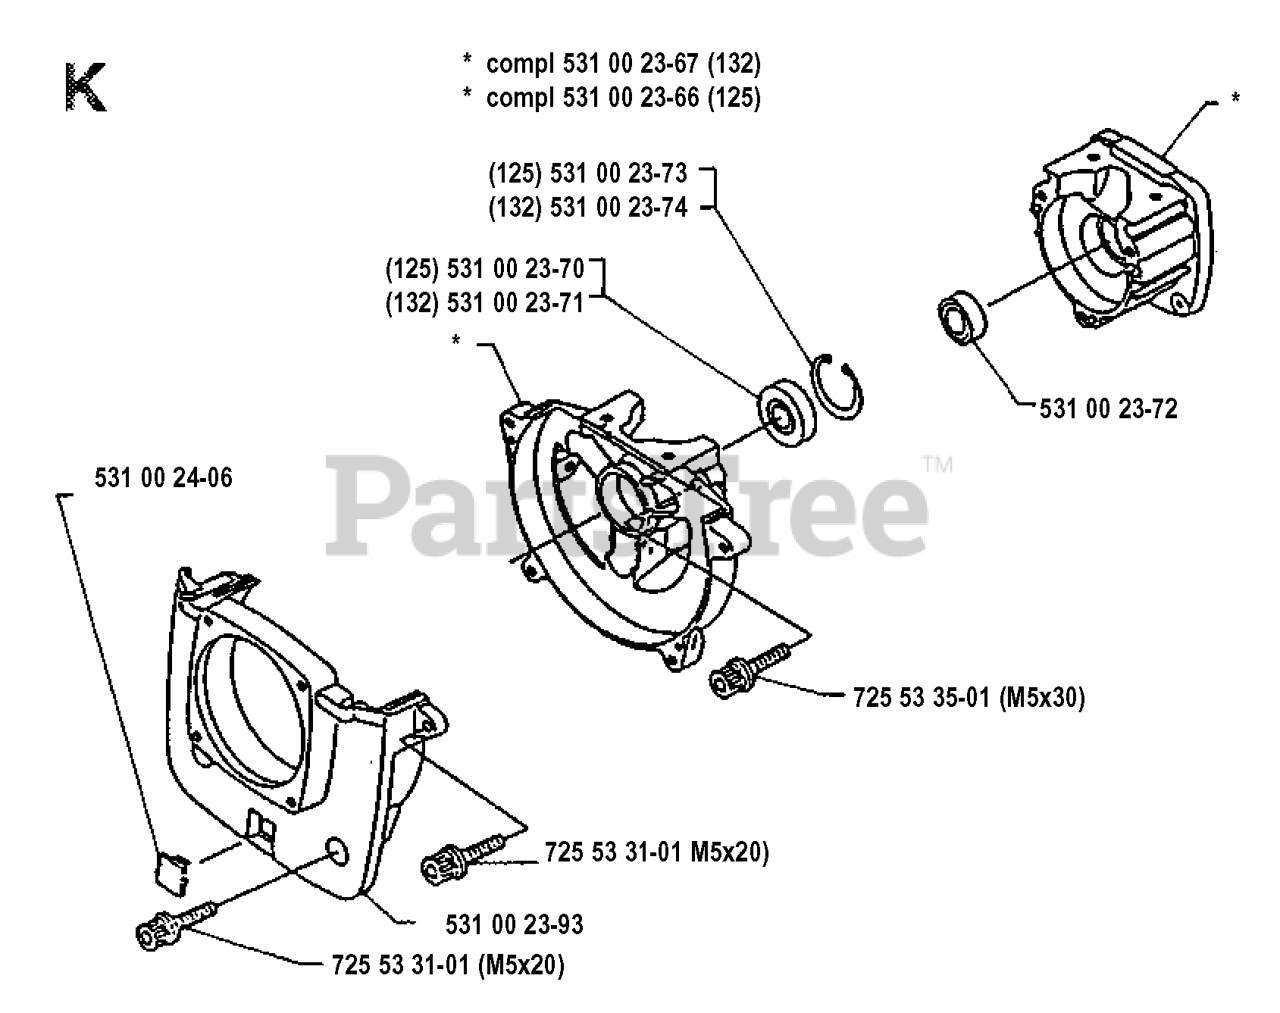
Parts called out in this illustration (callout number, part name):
2	CYLINDER PLUG
3	HQT-1 HH SPARK PLUG - BPMR7A
9	PISTON RING
11	WRIST PIN CLIP
12	SUPPORT BUSHING
